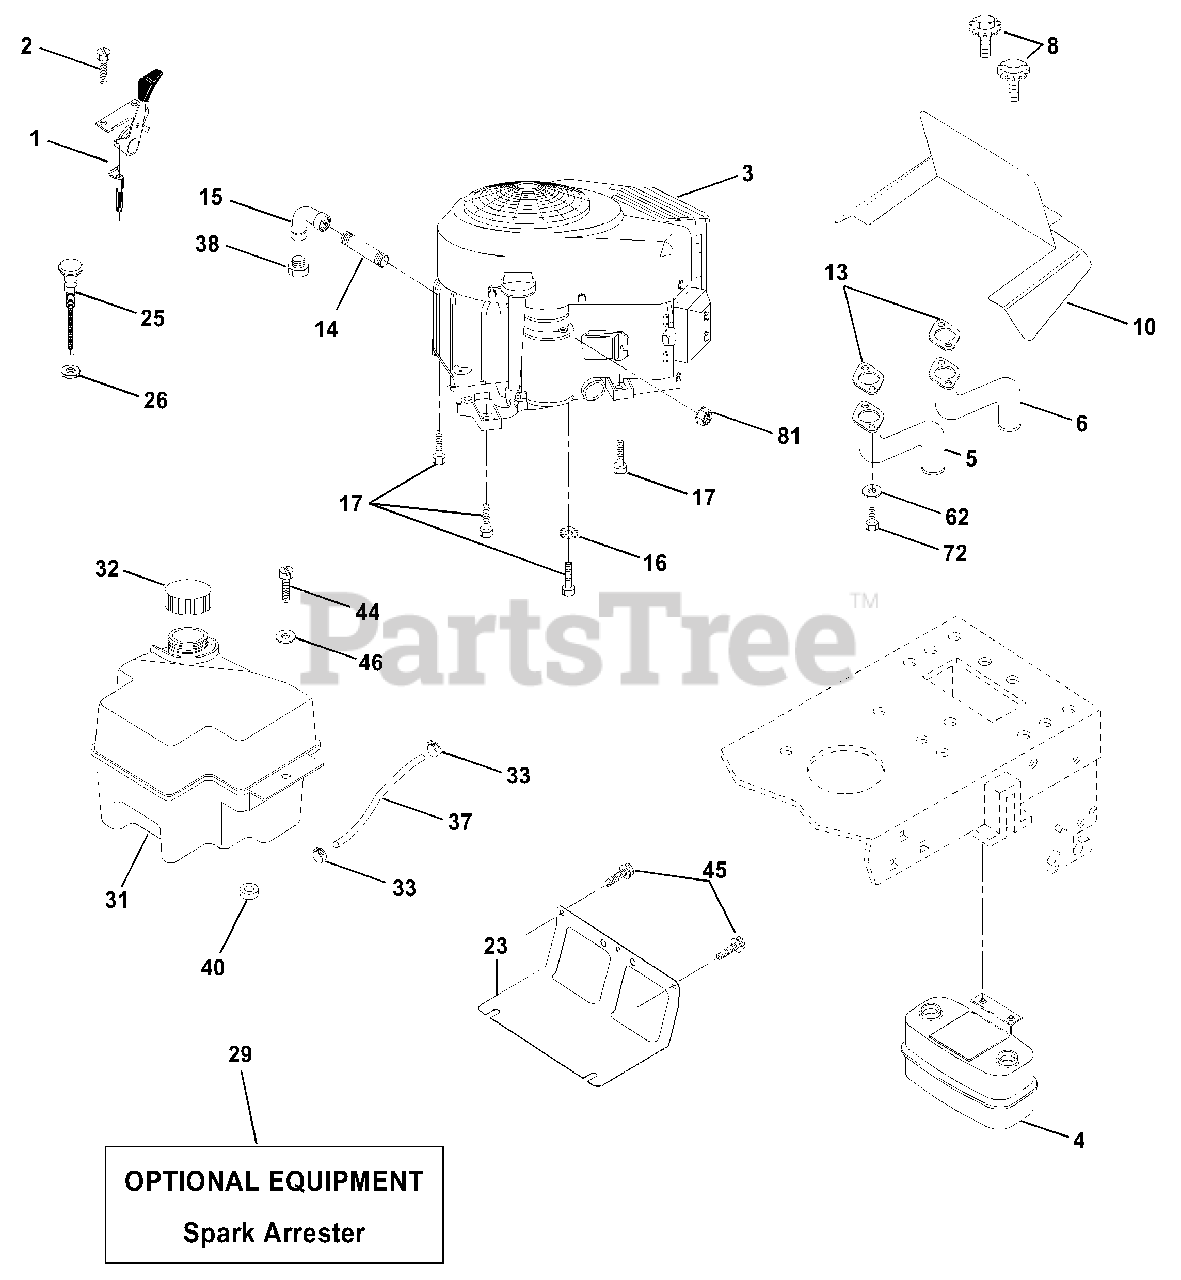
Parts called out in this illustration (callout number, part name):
1	Control Throt
2	Screw Hex Thd Cut 1/4-20 x 5/8 T
4	Muffler Exhaust
5	Exhaust Asm. Left
6	Exhaust Asm. Right
8	Bolt 5/16-18unc x 3/4 w/sems
10	Shield Heat
13	Gasket Muffler
14	Nipple Pipe 4-12"
15	Elbow Std 90 Degree 3/8-18 Npt
16	Washer Lock Ext Tooth 3/8
17	Screw Thdrol 3/8-16 x 1-1/2 Tytt
23	Shield Brn/Dbr Guard
25	Control Choke
26	Nut Keps 3/8-24 UNF
29	Arrestor Spark
31	Tank Fuel Front 2.00
32	Cap Fuel
33	Clamp Hose Blk
37	Line Fuel
38	Plug Oil Drain
40	Bushing Snap Nyl Blk Fuel Line
44	Screw Hex wsh Thdrol 1/4-20 x 3/4
45	Screw Hex Wsh Thdr 3/8-16 x 3/4
46	Washer 9/32 x 7/8 x 16 Ga.
62	Washer Lock Hvy HLCL Spr 5/16
72	Screw Hex Hd Cap 5/16-18 x 3/4
81	Nut Keps Hex 1/4-20 Unc
